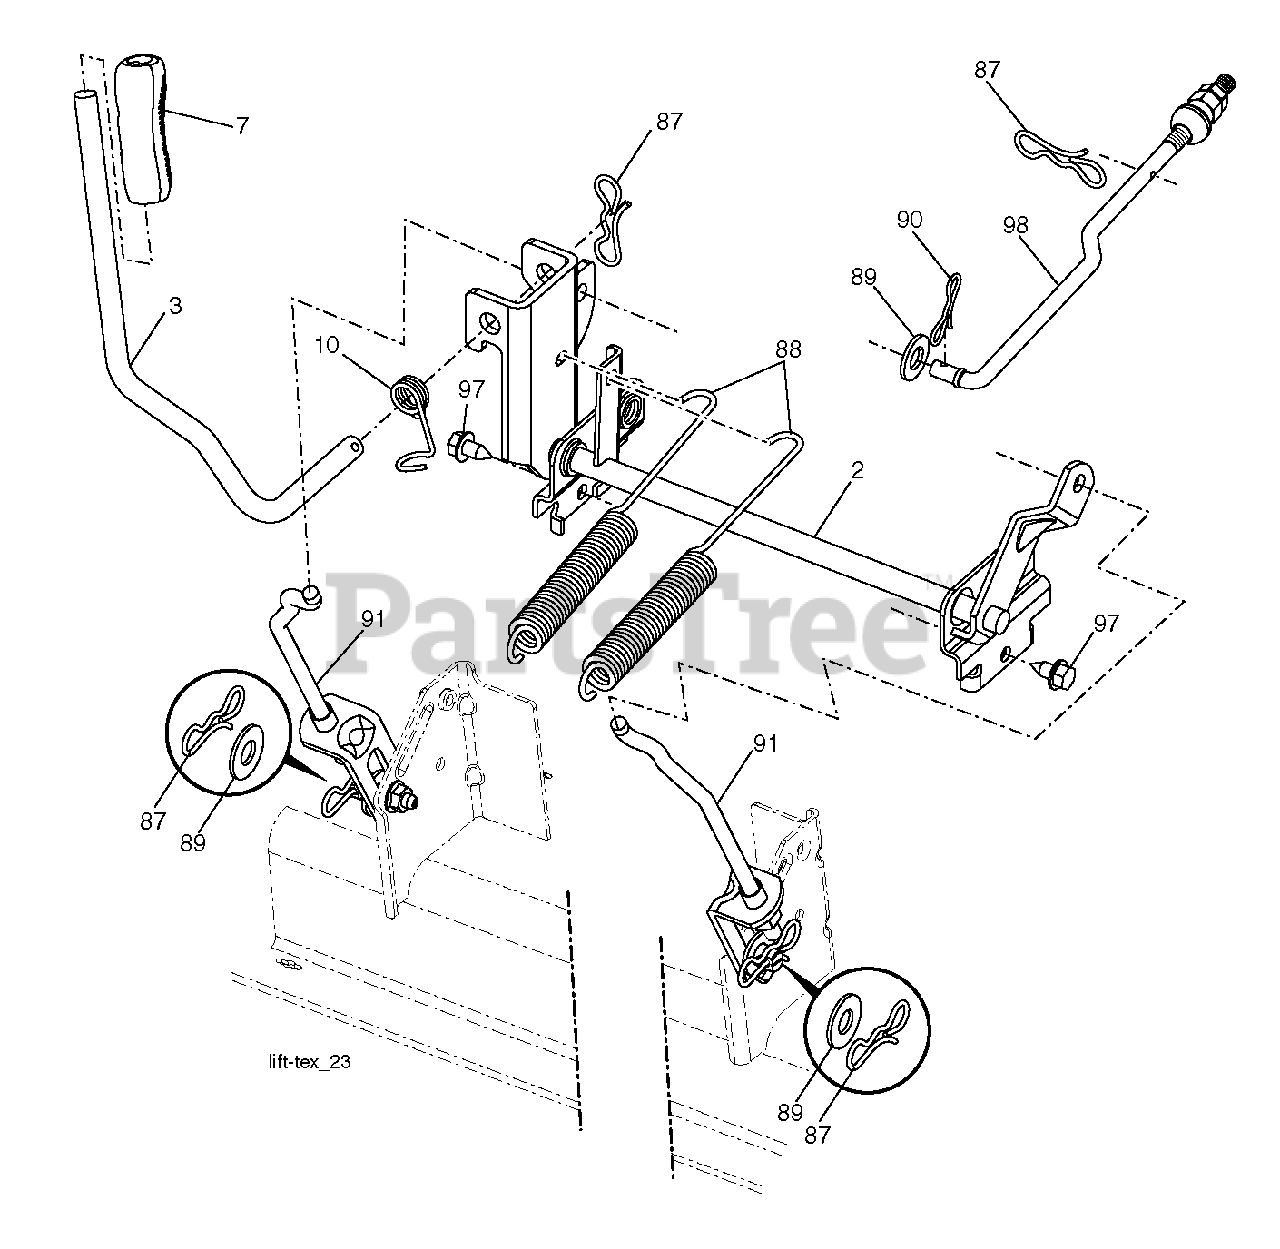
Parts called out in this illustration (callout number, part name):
2	SHAFT.ASM.CROSS.LIFT
3	LEVER.LIFT.HANDLE.GT
7	GRIP.HANDLE.LIFT.PVC.BLACK
10	SPRING.TORSION.LIFT.HANDLE
87	PIN.COTTER.7/16.BOW TI
88	SPRING.LIFT.ASSIST
89	WASHER.CLEAR.ZINC
90	PIN.COTTER.5/16.BOW TI
91	LINK.LIFT.ASM.REAR.GT.
97	SCREW, 3/8-16X3/4
98	LINK.ASM.SUSP.FRONT.MWR.10.5
